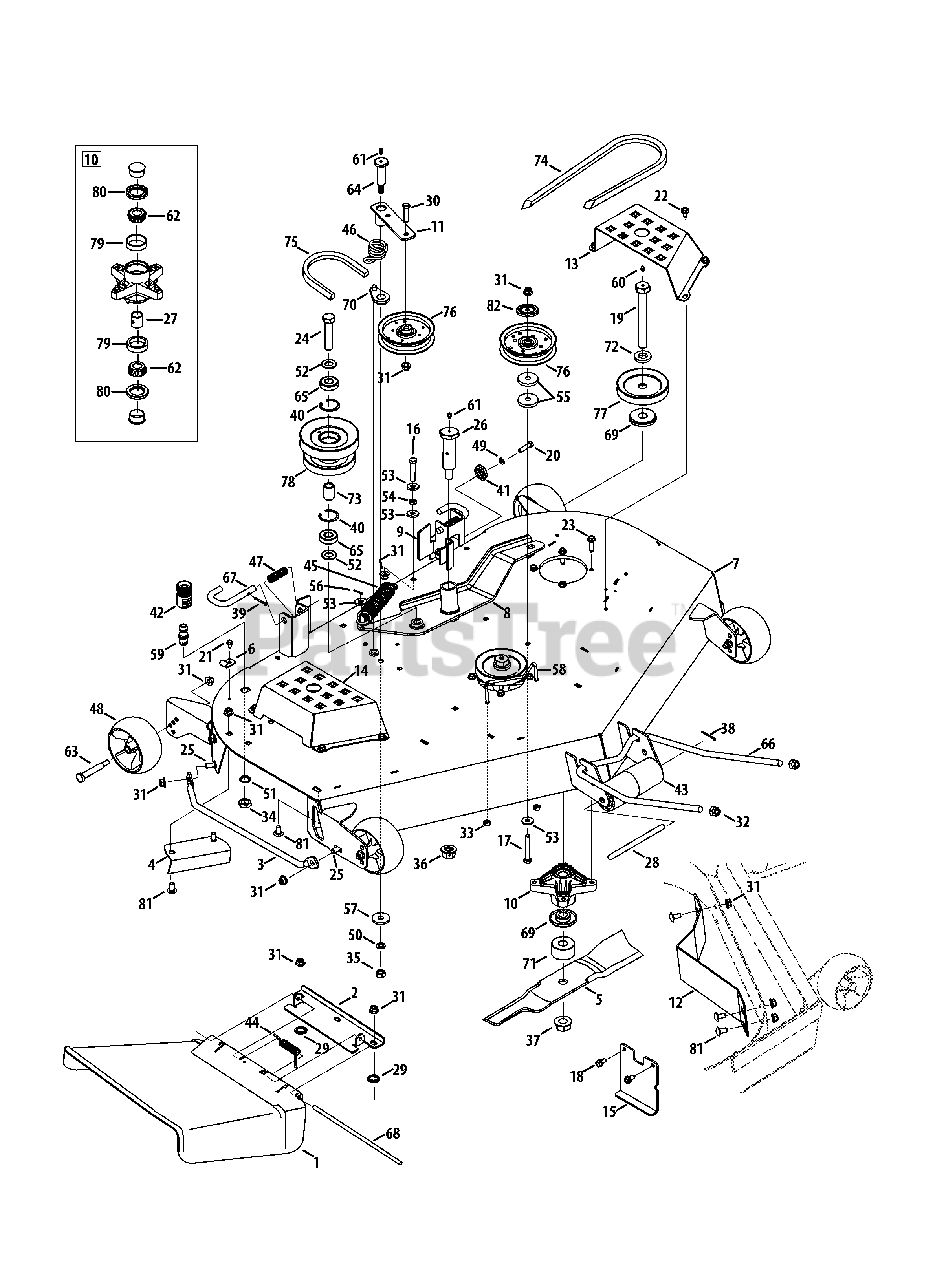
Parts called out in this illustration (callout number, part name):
1	Chute Deflector
2	Chute Bracket
3	Finger Guard
4	Micro Chute Baffle
5	Blade, 17"
6	Hook Retainer Bracket
7	Deck Assembly
10	Spindle Assembly
15	Up-Stop Bracket
16	Hex Screw, 3/8 x 16 x 1.75
17	Hex Screw, 3/8-16 x 2.50
18	Hex Washer, 5/16-18 x .750
19	Hex Screw, 3/4-16 x 6.00
20	Hex Screw, 5/16-18 x 1.25
21	Hex Washer Screw, 1/4-20 x .500
22	Hex Washer Screw, 5/16-18 x .625
23	Hex Washer Screw, 5/16-18 x 1.50
24	Hex Screw, 5/8-18 x 3.00
25	Carriage Bolt, 3/8-16 x 1.00
26	Shoulder Screw, 1.0 x 3.00
27	Bearing Spacer, .78 x 1.0 x 1.0425
28	Roller Pin, 1/2 x 7.31
29	Push Nut, 3/8
30	Hex Screw, 3/8-16 x 1.50
31	Flange Lock Nut, 3/8-16
32	Flex Lock Nut, 1/2-13
33	Hex Lock Nut, 1/4-20
34	Hex Nut, M16-1.5
35	Hex Nut, 7/16-14
36	Flange Lock Nut, 5/8-18
37	Flange Lock Nut, 3/4-16
38	Cotter Pin, 3/32 x 1.25
39	Cotter Pin, 5/32 x 1.25
40	Retainer Ring
41	Deck Adjustment Gear
42	Water Nozzle Adapter
43	Front Roller
44	Torsion Spring, 180 x .639 x 2.16 x .12
45	Extension Spring, 1.25 x 6.9
46	Idler Torsion Spring, 1.10 x 1.3
47	Compression Spring, .66 x 1.8
48	Deck Wheel, 5.0
49	Lock Washer, 5/16
50	Lock Washer, 7/16
51	Lock Washer, 5/8
52	Flat Washer, .65 x 1.25 x .075
53	Flat Washer, .385 x 1.0 x .135
54	Jam Nut, 3/8-16
55	Flat Washer, .4375 x 1.75 x .25
56	Cotter Pin, 3/32 x .75
57	Flat Washer, .45 x 1.5 x .172
58	Belt Drive Guard
59	Deck Water Nozzle
60	Grease Fitting, 1/4-28 x 3/16
61	Drive Lube Fitting, 3/16
62	Cone Bearing, .750
63	Shoulder Screw, 1/2 x 2.50
64	Shoulder Screw, 7/16-14 x .687 x 2.443
65	Ball Bearing, .625 x 40 x 12
66	Front Hanger Rod
67	Mower Support Pin
68	Chute Deflector Rod
69	Spindle Spacer
70	Spring Retainer
71	Spindle Spacer, .760 x 2.0 x 1.10
72	Spacer, .812 x .218
73	Spacer, .88 x .635 x 1.25
76	Idler Pulley
78	Double Pulley
79	Bearing Cup, .750
81	Carriage Bolt, 3/8-16 x .75
82	Pulley Cap
